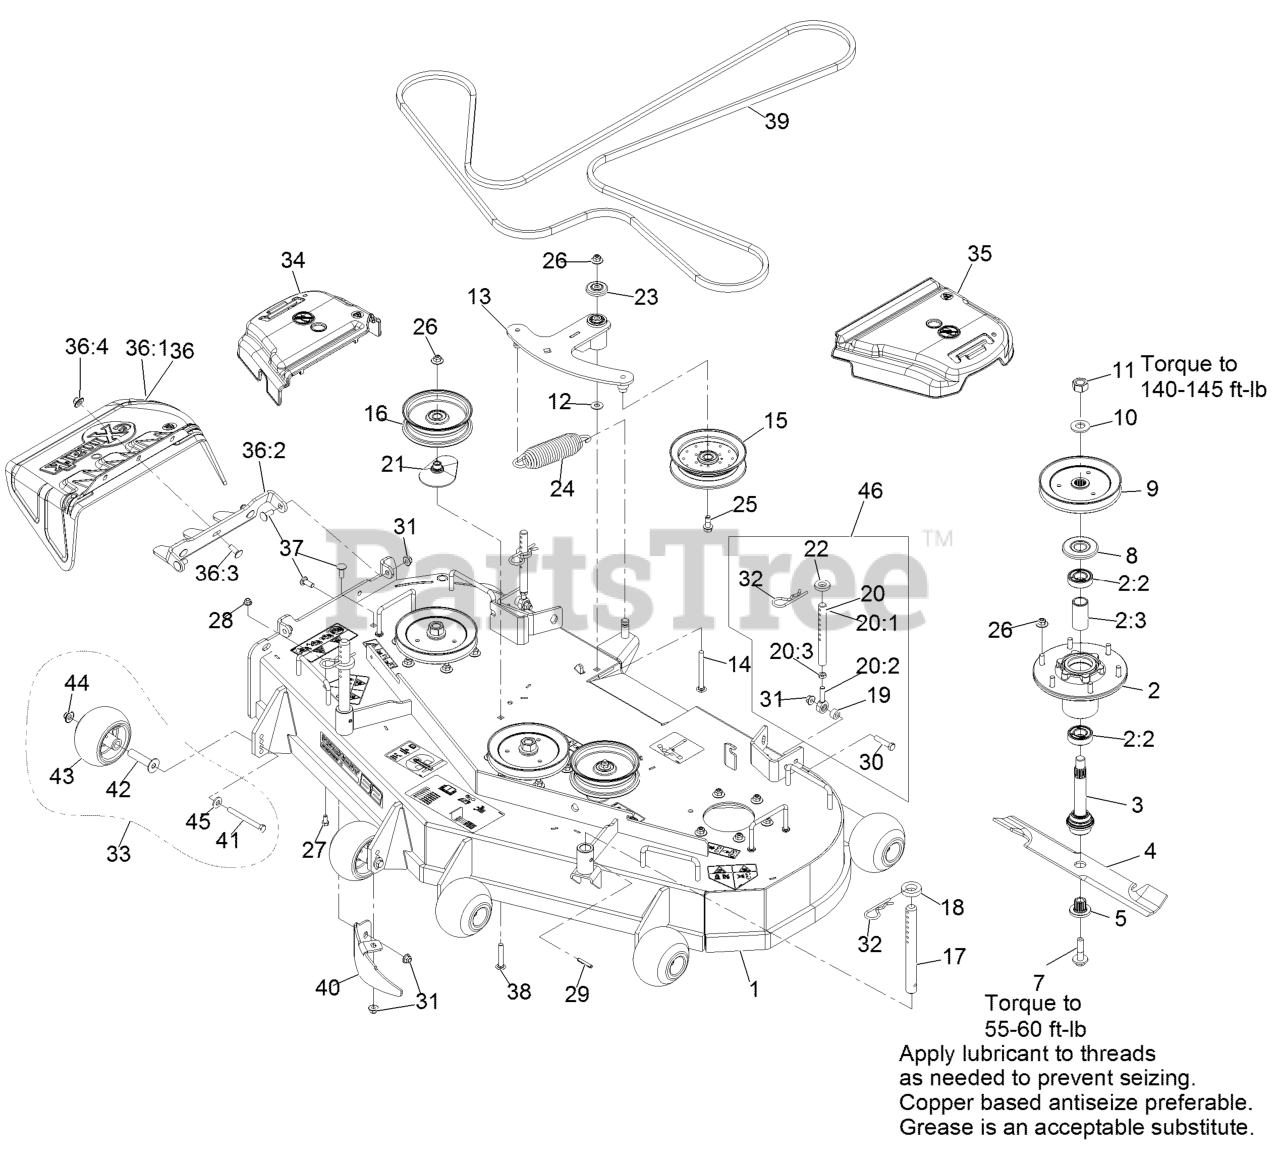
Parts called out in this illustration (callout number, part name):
1	ASM, DECK W/ DECALS, 52"
2	ASM-CUTTER HSG WITH BEARINGS
2:2	BEARING-BALL
2:3	SPACER-BEARING
3	ASM-SPINDLE AND SEAL
5	BUSHING,SPLINED
7	SCREW,SEMS 1/2-20 X 2.19
8	GUARD,BEARING TOP .989
9	SHEAVE,BLADE DRIVE 6.50
11	NUT-HEX
12	WASHER-FLAT
13	ASM, DECK IDLER
14	SCREW-CARR
16	IDLER-PULLEY, FLAT
17	ROD,DECK SUPPORT
18	SPACER-DECK SUPPORT
20:1	LINK,SUPPORT
20:2	BALLJOINT
20:3	NUT-HJ
21	SPACER-PULLEY
23	GUARD-TOP
24	SPRING-EXTENSION
25	SCREW-HFH
26	Nut-Nyloc 3/8-16 Flg
27	SCREW-HH
28	NUT-HF, NI
30	SCREW-HH
31	NUT-HF, NI
32	PIN,HAIR COTTER
33	KIT, ANTI-SCALP ROLLER
34	COVER-BELT, RH
35	COVER-BELT, LH
36	ASM,DISCHARGE CHUTE
36:1	CHUTE,DISCHARGE
36:2	BRACKET,DISCHARGE CHUTE
36:3	SCREW-CARR
36:4	Nut-Nyloc 3/8-16 Flg
37	SCREW-CARR
38	BOLT-CARR, SHORT NECK
39	BELT, DECK DRIVE
40	BAFFLE-DOGLEG, LZ-VT52
41	SCREW-HH 3/8-16 X 3 3/4 GR 8
42	AXLE, ROLLER
43	ROLLER-SCALP, ANTI
44	Nut-Nyloc 3/8-16 Flg
45	WASHER-BELLEVILLE
46	KIT,SUPPORT LINK W/PIN
